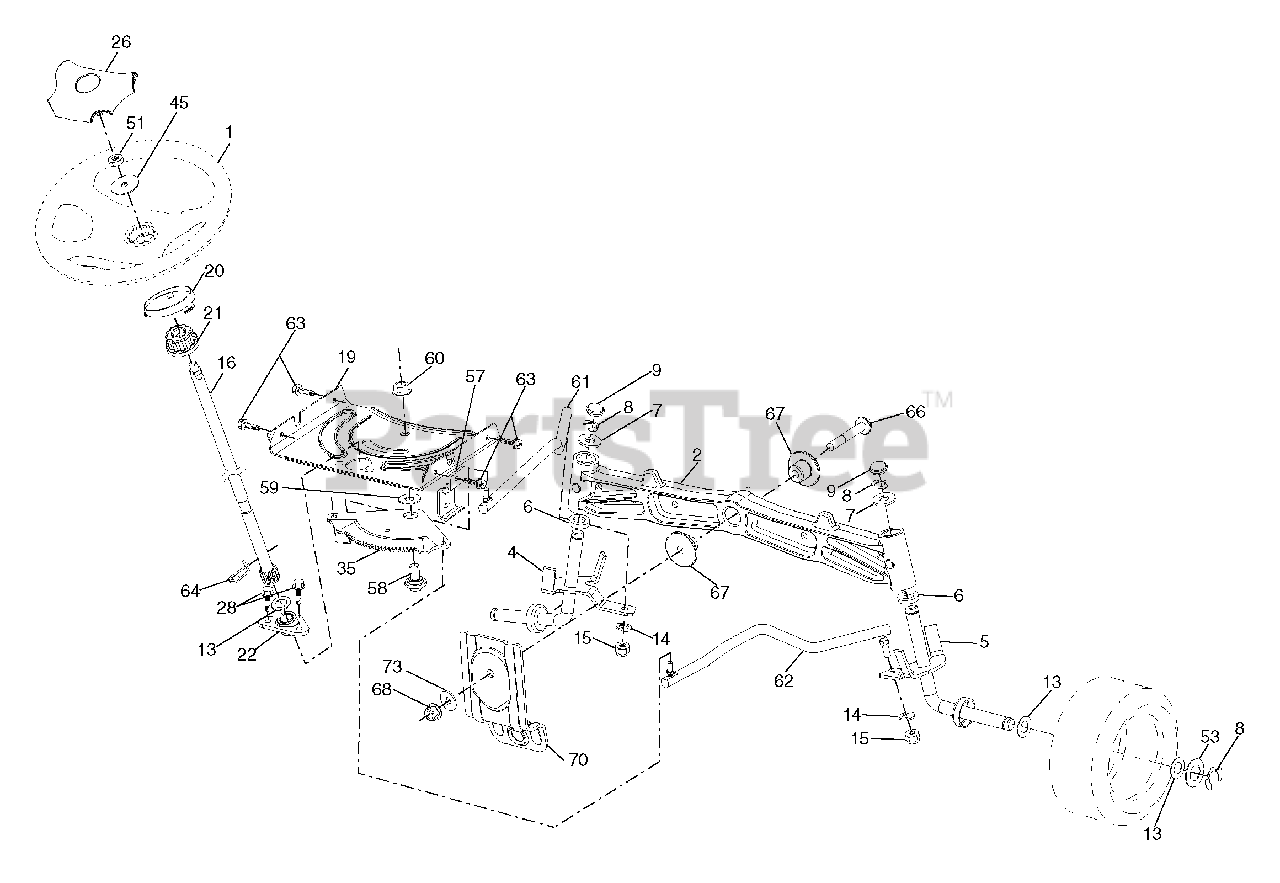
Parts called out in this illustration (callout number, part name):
1	Wheel, Steering
2	Axle Asm., Front
4	Spindle Asm., LH
5	Spindle Asm., RH
6	Bearing, Race Thrust Harden
7	Washer 25/32 x 1-5/8 x 16 Ga.
8	Ring, Klip #T5304-75
9	Cap, Spindle
13	Washer 25/32 x 1-1/4 x 16 Ga.
14	Washer, Lock Hvy Hlcl Spr 3/8
15	Nut, Crown Lock 3/8-24 unf
16	Shaft Steering
19	Plate Steering
20	Boot, Steering
21	Adapter, Wheel Steering
22	Bushing, Strg. Blk
26	Insert, Wheel Steering
28	Screw 3/8-16 x 3/4
35	Gear, Sector Plate
45	Washer 9/16 x 2-3/8 x 12 Ga.
51	Nut Hex Jam Toplock 1/2-20 unf
53	Washer Hardened.793 x 1.37 x .060
57	Bracket Upstop
58	Bolt Shoulder Sector Pivot CFM
59	Washer Thrust Sector Steering
60	Nut Flange Lock 5/8-11
61	Draglink LH
62	Draglink, RH
63	Screw 5/16-18 x 3/4
64	Retainer Clip Spring Steering
66	Bolt Hex Fghd 7/16-14 x 3 Serr
67	Bushing PM Front Axle
68	Nut Lock Flange 7/16-14 Gr. 5
70	Bracket Deck Susp. Front
73	Washer 1/2 x 1-1/4 x 14 Ga.
